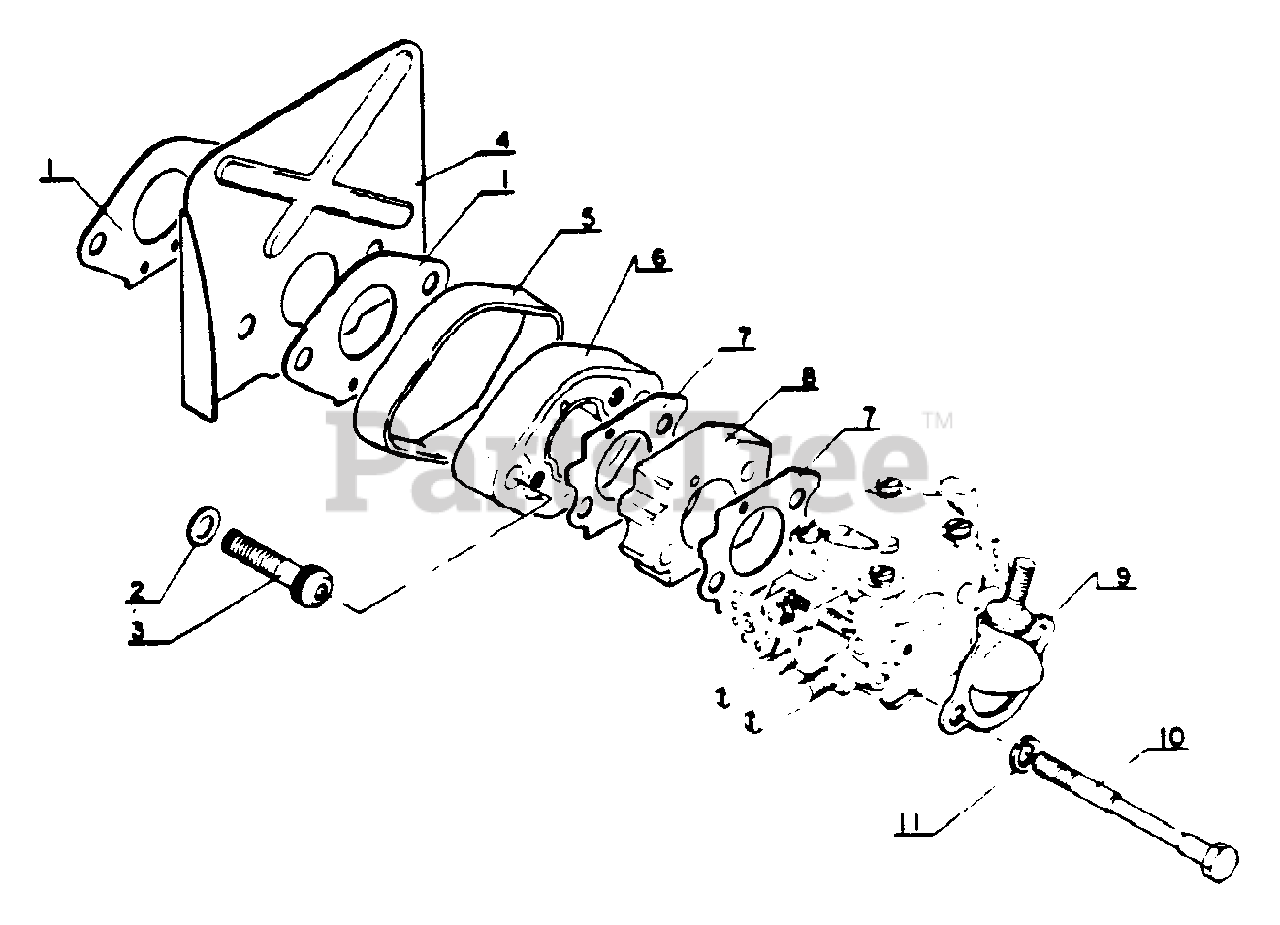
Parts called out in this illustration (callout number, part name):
3	BOLT - 6×28
4	PLATE, WIND PROOF
6	CASE, CARBURETOR
8	INSULATOR
9	PLATE, PREVENT
10	BOLT
11	WASHER, SPRING 5
